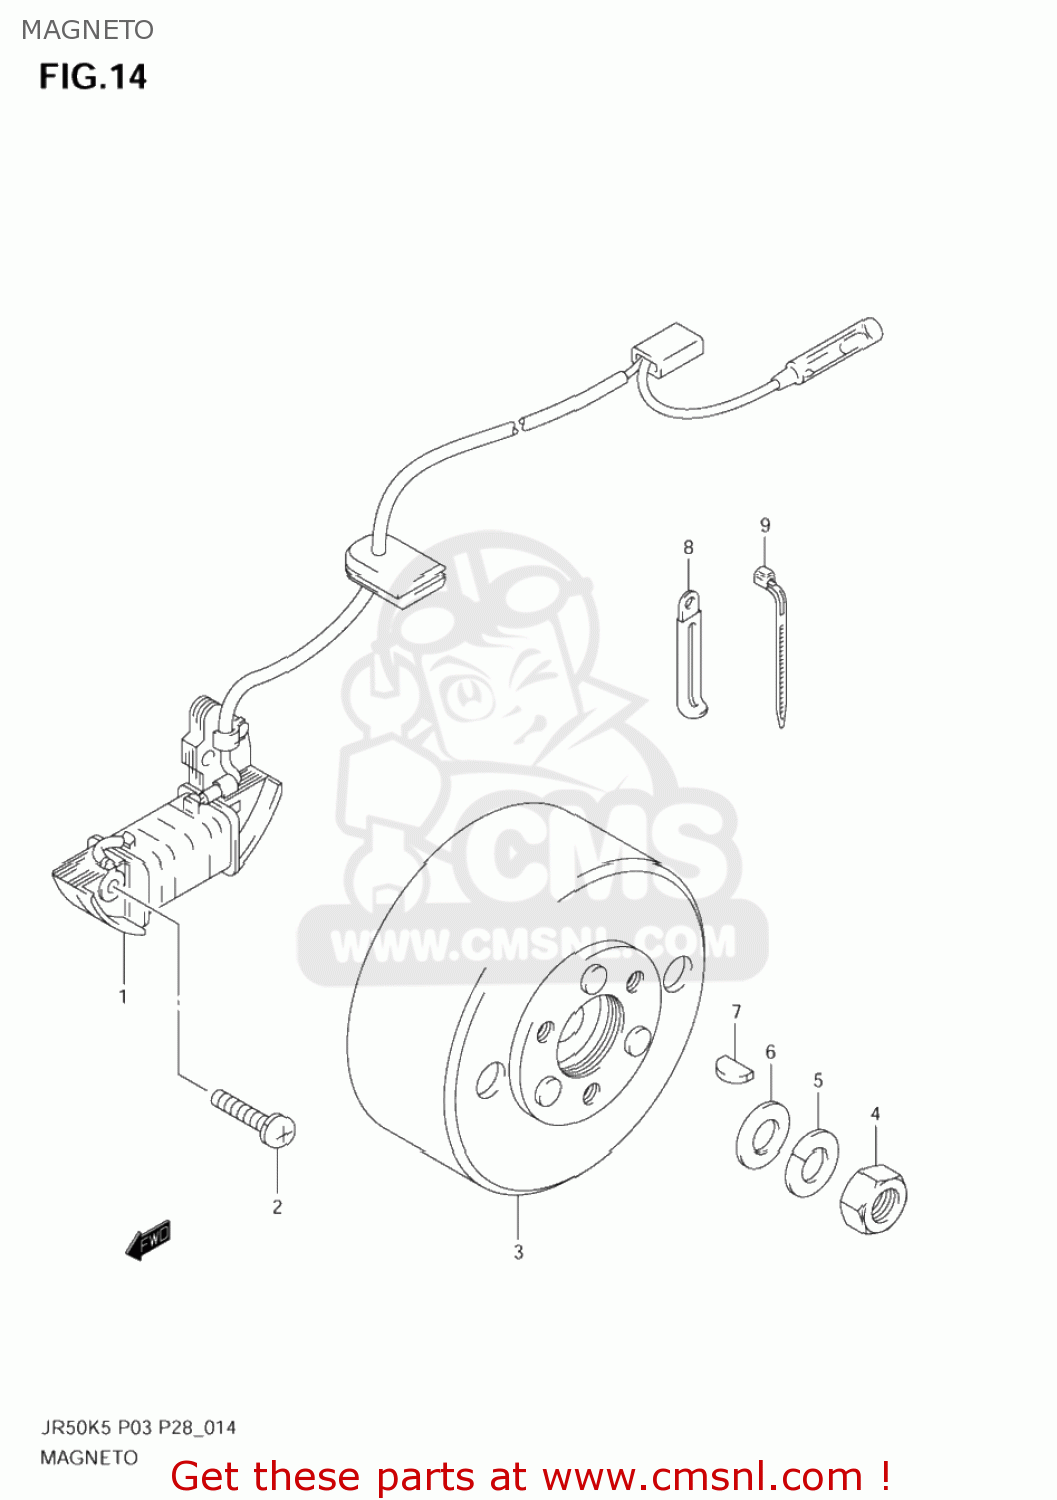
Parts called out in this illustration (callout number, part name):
1	STARTER ASSY
2	SCREW
3	ROTOR ASSY
4	NUT
5	WASHER
6	WASHER
7	KEY
8	CLAMP(L:45)
9	CLAMP(L:165)
